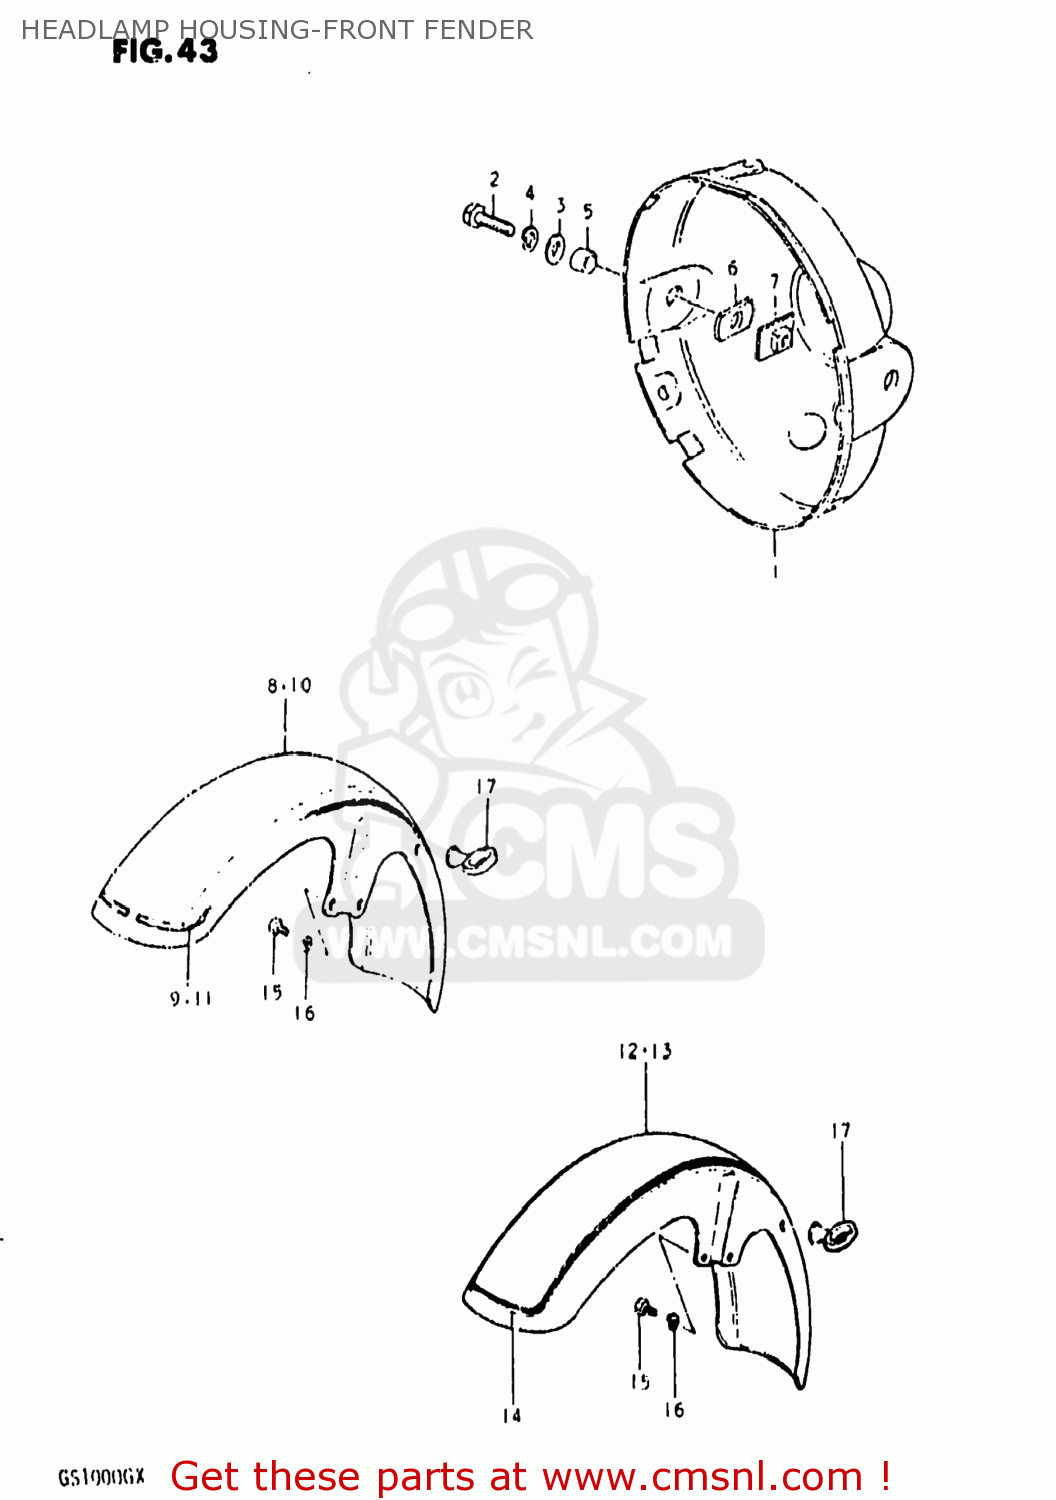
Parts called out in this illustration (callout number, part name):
1	HOUSING,HEADLAMP(BLACK)
2	BOLT
3	WASHER
4	LOCK WASHER
5	SPACER (8.8X12X7)
6	CUSHION
7	PLATE,HEADLAMP HOUSING
8	FENDER,FRONT
9	TAPE,FRONT FENDER
10	FENDER,FRONT
11	TAPE,FRONT FENDER
12	FENDER,FRONT
13	FENDER,FRONT
14	TAPE,FRONT FENDER
15	BOLT
16	LOCK WASHER
17	GUIDE,CABLE
